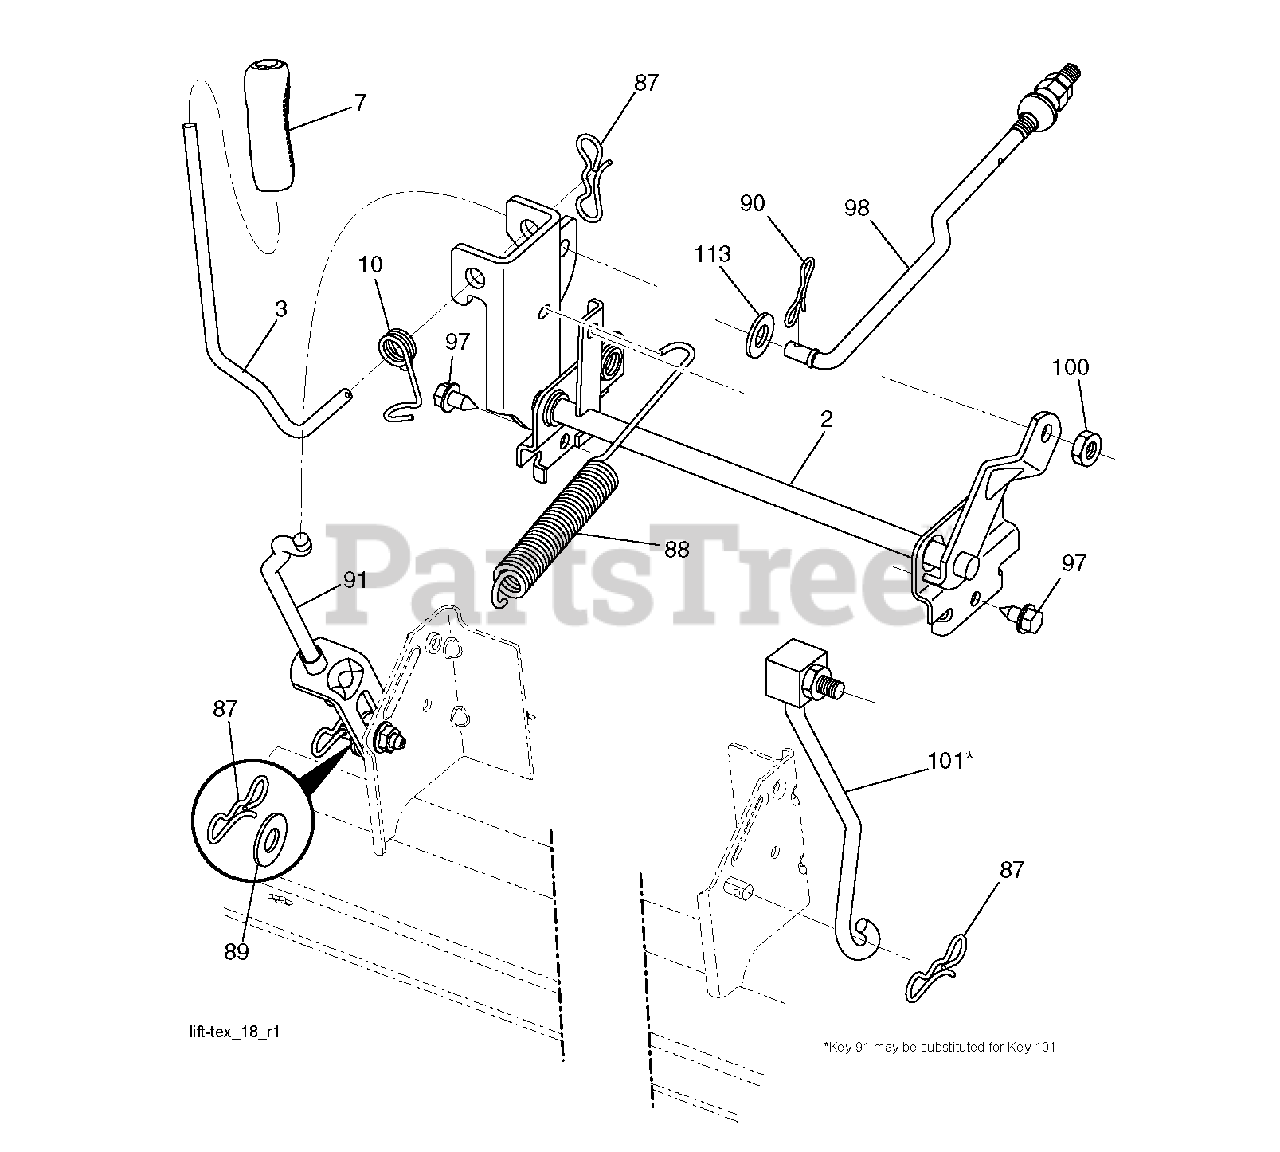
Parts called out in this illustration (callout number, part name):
2	SHAFT.ASM.CROSS.LIFT
3	LEVER.LIFT.HANDLE.LT
7	GRIP.HANDLE.LIFT.PVC.BLACK
10	SPRING.TORSION.LIFT.HANDLE
87	PIN.COTTER.7/16.BOW TI
88	SPRING.LIFT.ASSIST
89	WASHER.CLEAR.ZINC
90	PIN.COTTER.5/16.BOW TI
91	LINK.ASM.LIFT.REAR
97	SCREW, 3/8-16X3/4
98	LINK.ASM.SUSP.FRONT.MWR.10.5
100	LOCKNUT
101	LINK.ASM.LIFT.FIXE.38/42/46"
